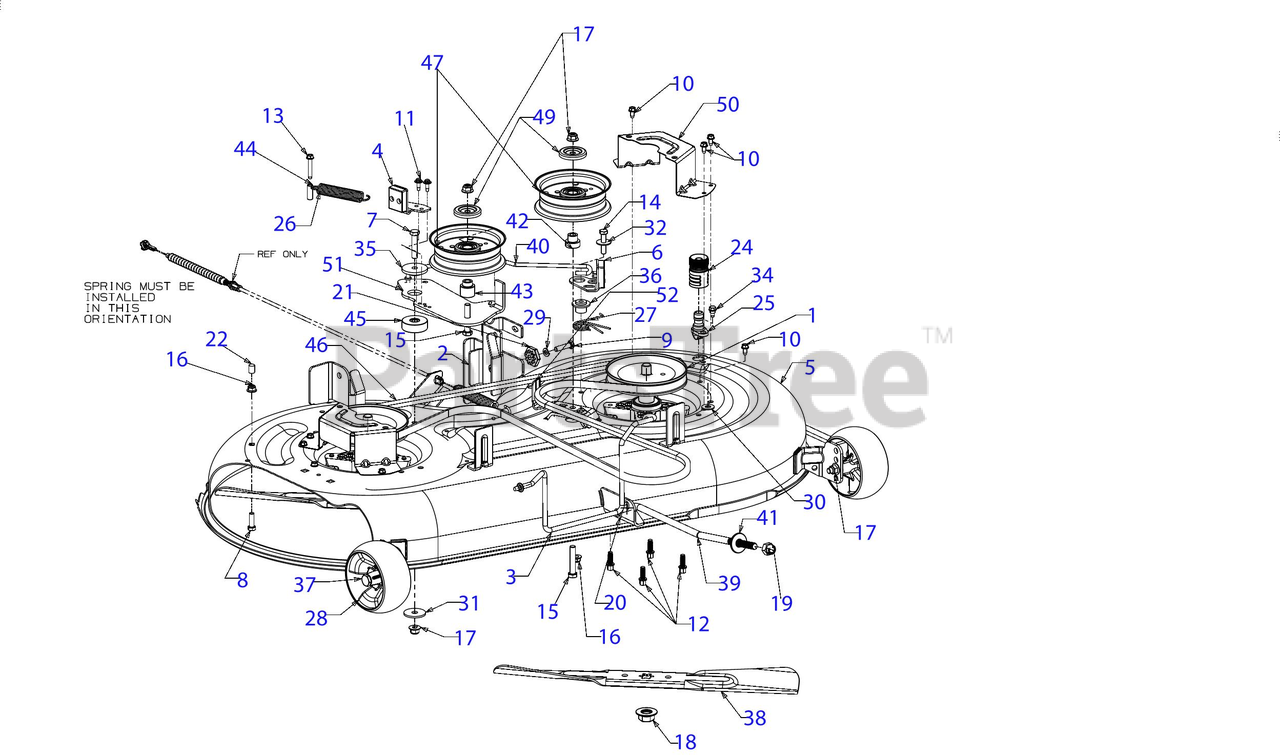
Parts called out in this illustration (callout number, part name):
1	SPINDLE ASSEMBLY
1	Troy-Bilt 42" SPINDLE ASSEMBLY (06991)
3	BELT KEEPER ROD
4	DECK BRAKE ASSEMBLY (RH)
7	HEX SCREW 3/8-16 x 1.75 GR5
8	SCREW 5/16-18 x 1.0 GR5
9	SCREW 5/16-18 x 1.25 GR5
10	SCREW 1/4-20 X.500
11	SCREW M6-1 x .625
12	SCREW 5/16-18 X .875
13	SCREW 1/4-20 x 1.50"
14	SCREW 5/16-18 x 1.5 LG
15	SCREW 3/8-16 x 2.0 GR 8
16	FLANGE LOCK NUT 5/16-18
20	PIN:COTTER
24	WATER NOZZLE
25	DECK WASH NOZZLE
26	EXTENSION SPRING
27	TORSION SPRING
28	DECK WHEEL
28	WHEELS-DELUXE 5"
29	LOCK WASHER 5/16
30	FLAT WASHER
31	FLAT WASHER .406X1.500X.105
32	FLAT WASHER 344X1.00
34	SHOULDER SCREW 1/4-20X.50 19"PSH
35	SHOULDER SPACER
36	DOUBLE SHOULDER SPACER .750 X .135
37	SHOULDER BOLT
38	21.23" BLADE (2N1)
38	Cub Cadet 42" BLADE SET
38	Genuine Factory Parts 42" BLADE SET(2N1)
38	21.23" BLADE (2N1) (XTREME)
38	42" 6 PT STAR LOW LIFT/SAND BLADE
39	DECK FRONT LIFT ROD
40	DECK BRAKE ROD
41	DECK LIFT PIVOT CUP
42	SHOULDER SPACER
43	SHOULDER SPACER
45	SPACER .385ID x 1.75OD x .585THK
46	V-BELT A x 96.5
46	Genuine Factory Parts 42" DECK DRIVE BELT
47	IDLER PULLEY 4.50" DIA
49	IDLER PULLEY CAP
51	DECK IDLER BRACKET
